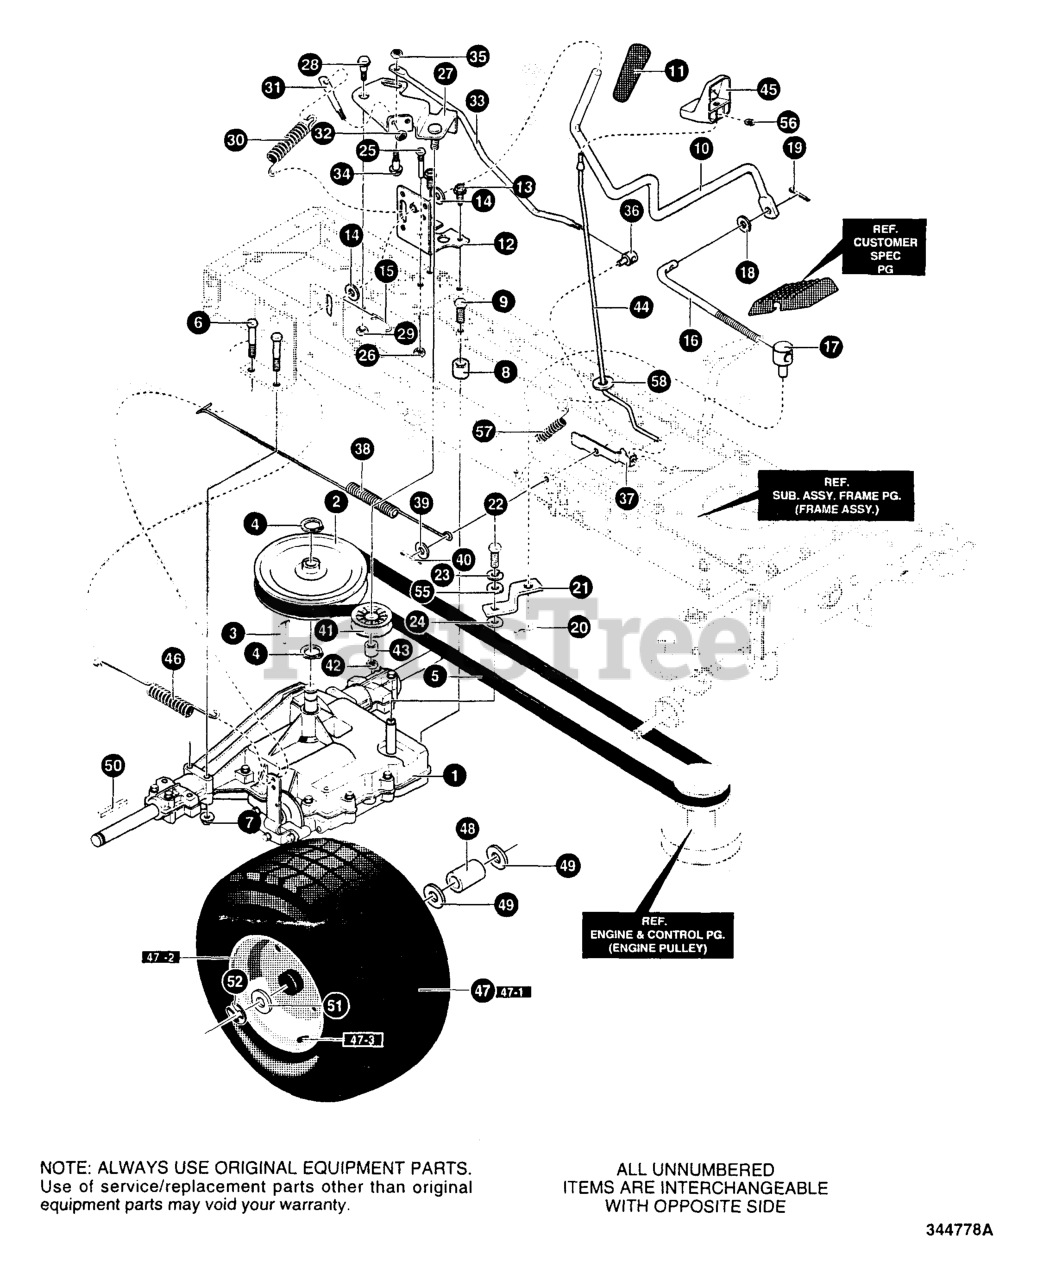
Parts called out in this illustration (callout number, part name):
1	Transaxle, Peerless **
2	PULLEY, 8.81 DIA.
3	KEY WDRF #9 .75DIAX.18X.310
4	RING, RETEX.58X.04 TRU (11X7)
5	BELT, V (37X87)
6	SCREW, 5/16-18 x 2.50
7	NUT, 5/16-18 WDFLLK
8	SPACER,TRANSAXLE
9	SCREW, 5/16-18 X 2.00 HHTFT
10	LEVER, SHIFT EXTENDED
11	GRIP, LIFT 1/2" ID
12	BRACKET, SHIFT PIVOT
13	SCREW, 5/16-18 x 0.75 HHWATAP
14	WASHER, FLAT .518 x .87 x 16
15	PIN, HAIR
16	LINK, SHIFT
17	NUT, ADJ 3/8-16 TAP
18	WASHER, FLAT .406 x .81 x 16 GA
19	PIN, COTTER .094DIAX.75
20	PIN, HAIR.38X DIA.X1.64LG
21	YOKE-SHIFT
22	SCREW, 1/4-28X.750HHC
23	WASHER (18X32)
24	WASHER .388X.393SQX1.00X.065
25	SCREW GUIDE 5/16-18
26	NUT 5/16-18 HEXHDFLLK WHIZ
27	ARM, Idler
28	BOLT, .50X.75 HHSH 3/8-16
29	NUT, 3/8-16 HWDFLLK MACK
30	SPRING, EXTENSION 5.16LG
31	STUD-SPRING MTG
32	NUT, 5/16-18 HEXHDFLLK WHIZ
33	ROD. CLUTCH SWITCH
34	BOLT,.50X.75 HHSH 3/8-16
35	NUT, 1/4-20 WDFLLK
36	NUT, ADJUSTING
37	LATCH, PARK BRAKE
38	SPRING, EXTENSION
39	WASHER, FLAT .406X.81 X16GA
40	PIN, COTTER .094DIAX.75
41	PULLEY, IDLER 2.75 DIA
42	NUT, 3/8-16 HWDFLLK MACK
43	SPACER 1/2 TO 17MM
44	ROD, PARKING BRAKE
45	KNOB, PARKING BRAKE
46	SPRING, TENSION 3.984X.530
47	TIRE & RIM 20X10-8
47-1	TIRE 20X10-8
47-2	RIM, CARL
47-3	VALVE STEM
48	SPACER, .87X1.78 87X105
49	WASHER, FLAT .760 x 1.25 x .065
50	KEY, SQUARE.187QX2.0LG
51	WASHER, FLAT .765 x 1.81 x .059
52	E-RING.574IDX.050/.750SH 11X3
53	HUB CAP 8" W/O HOLE
54	CLIP, HUBCAP TINNERMAN
55	FLATWASHER.256X.75X.130Z
56	PUSHNUT, .240DIAX STUD
57	SPRING, TENSION .375X1.50X.
58	WASHER, FLAT .286X.63X.065
